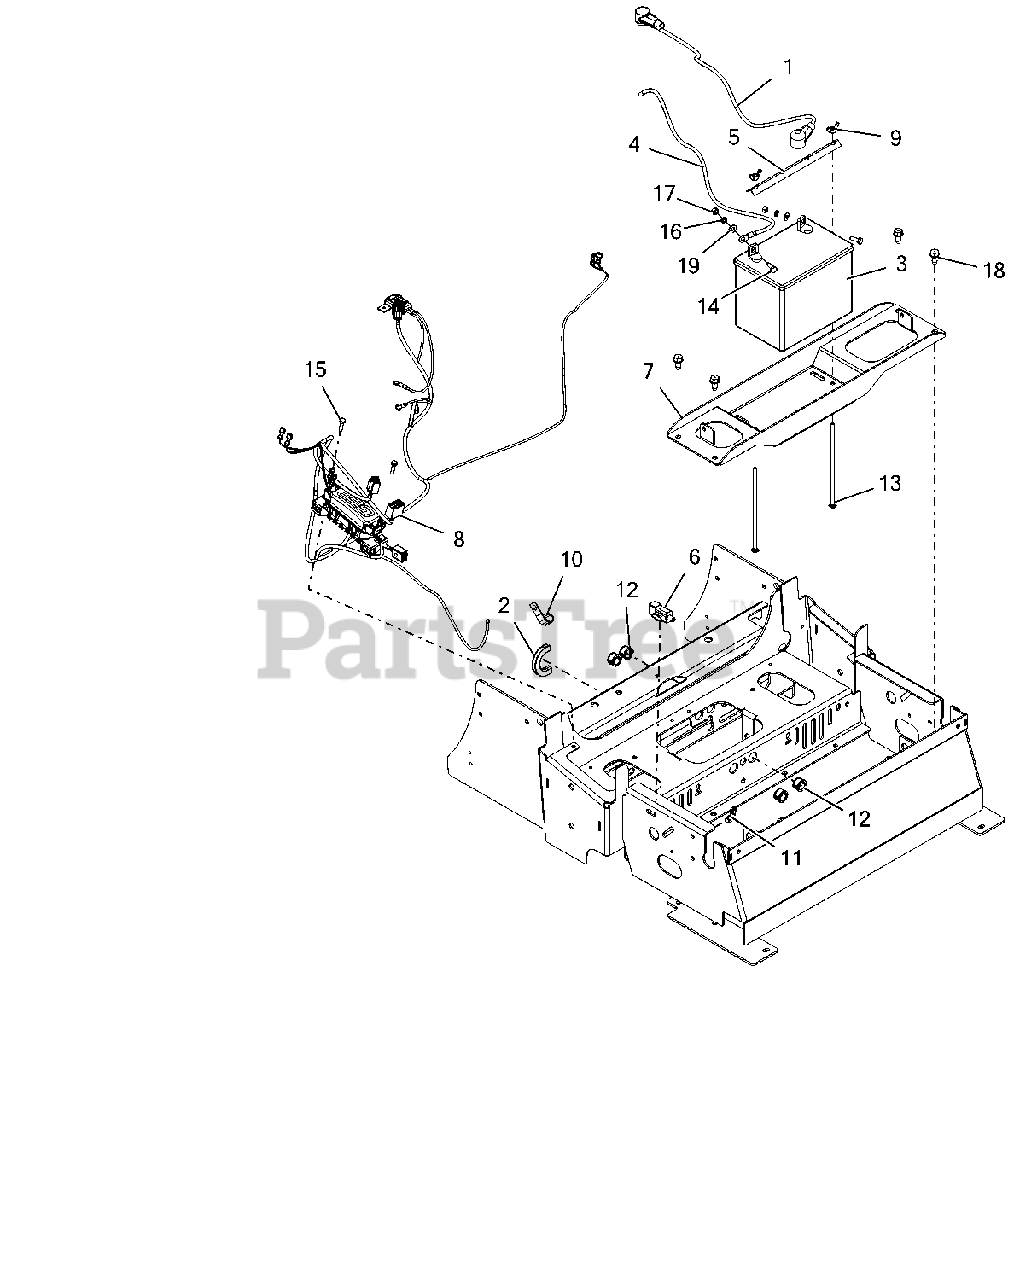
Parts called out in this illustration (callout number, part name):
1	CABLE - POS BATT W/BOOTS 6X35
2	STRIP, COWL
3	BATTERY, 300 CCA 10U1L
4	CABLE-NEGATIVE BATTERY 35.00"
5	HOLD DOWN
6	SWITCH, SNAP IN - N.O./N.O.
7	PT400 GAS BATTERY TRAY - RED
8	HARNESS, PT400 WIRING
9	NUT-LK WING .250-20 YWZC
11	CABLE TIE W/ TREE (.25 HOLE)
12	BUSH, PANEL SNAP .687X.875X.56
13	BLT-RDHDSQNK .25-20X7.50 GR2YZ
14	@BLT-HEX .25-20X.75 GR5 YWZC
15	@BLT-HEX M6-1.0X25 YWZC
16	@WSHR-LK .25X.062 REG YWZC
17	@NUT-HEX .25-20 YWZC
18	@SCR-TAP .38-16X.75 HWH TR YWZ
19	@WSHR-FL-STL.281X.62X.065 YWZC
